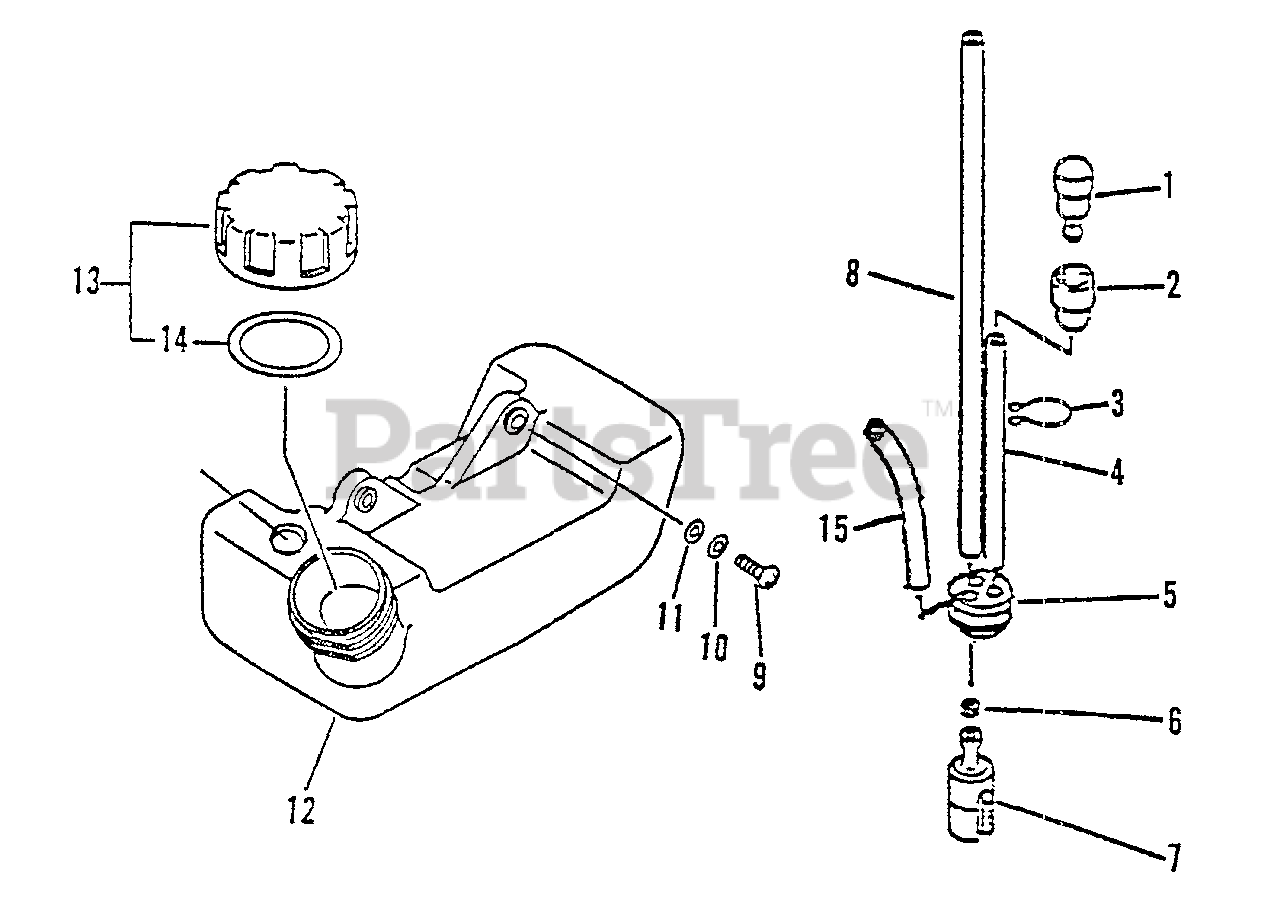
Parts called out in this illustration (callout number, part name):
1	VENT, FUEL TANK
2	COVER, VENT
4	PIPE - 3X5X70 -- BLACK
5	GROMMET
6	CLIP - 6
7	FILTER, FUEL
8	PIPE - 3X5X180 -- BLACK
9	SCREW - 5X16
10	LOCKWASHER - 5
11	WASHER - 5
12	TANK, FUEL
13	CAP ASSY
14	GASKET, CAP
15	PIPE - 3X6X90 -- CLEAR
